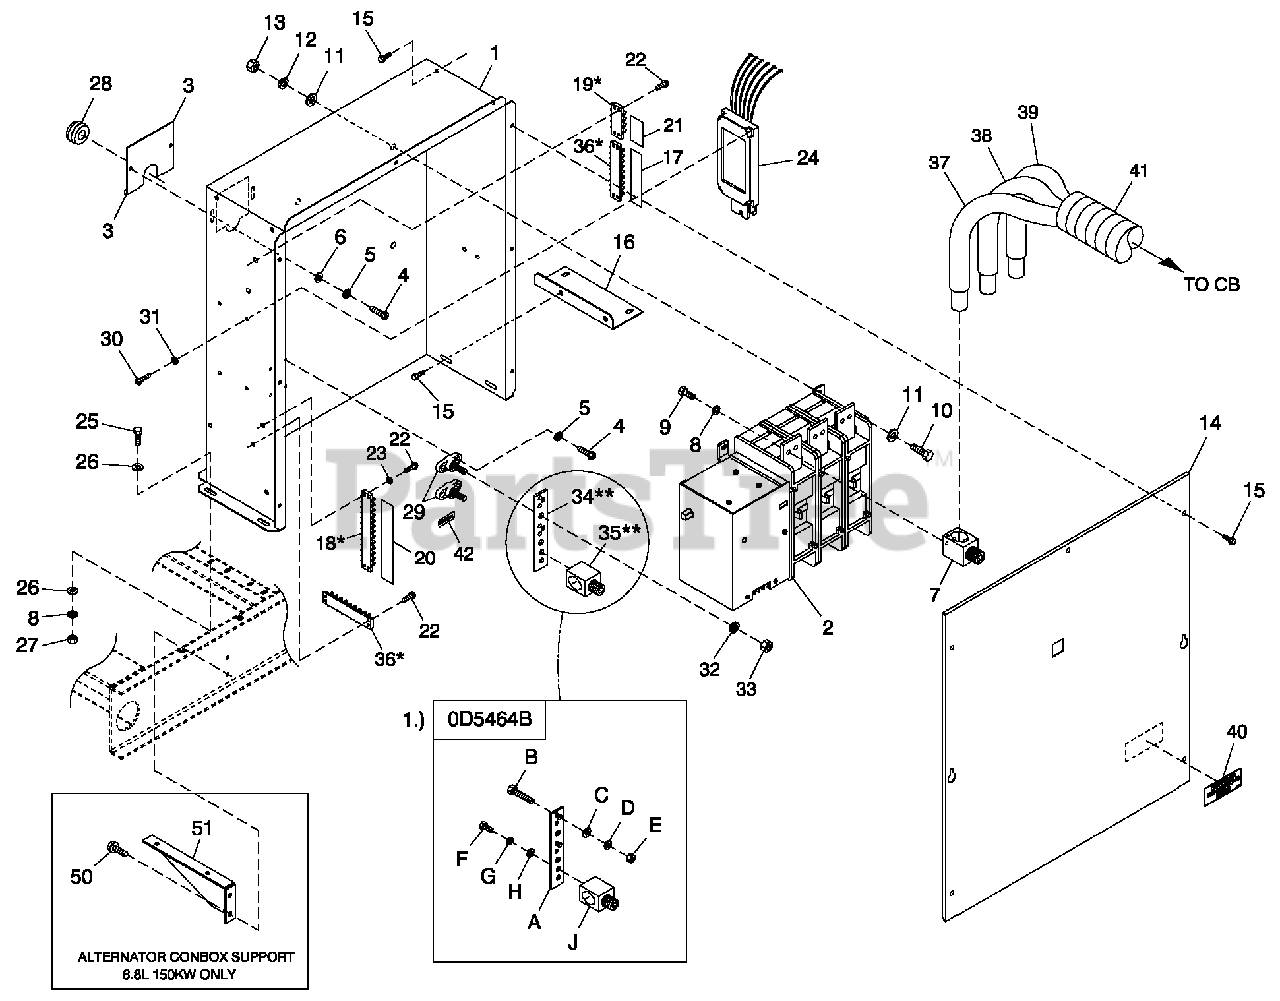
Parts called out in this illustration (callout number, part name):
1	CONBOX CONTACTOR 400A
2	CONTACTOR 400A 3P AC CL DC TR
3	PLATE WIRE SNGLGALV
4	SCREW PHTT M5-0.8 X 16 ZYC
5	WASHER LOCK M5
6	WASHER FLAT M5
7	LUG SLDLSS 600/250-1/0X1/4-28
8	WASHER LOCK M6-1/4
9	SCREW HHC 1/4-28 X 5 /8 .625TH
10	SCREW HHC M8-1.25X 20 G8.8
11	WASHER FLAT 5/16-M8 ZINC
12	WASHER LOCK M8-5/16
13	NUT HEX M8-1.25 G8 CLEARZINC
14	COVER CONTACTOR 400A
15	SCREW THF M6-1 X 16 N WA Z/JS
16	MOUNT CONTACTOR
17	DECAL GEMINI PLS CONNECTIONS
18	BLOCK TERM 2 0A 12 X 6 X1100V
19	BLOCK TERM 20A 6 X 3 X1100V
20	DECAL CUSTOMER CONNECTION
21	DECAL CUSTOMER CONNECTION 120V UTILITY
22	SCREW PHTT #6-32 X 1/2 ZYC
24	ASSY PCB 3PH VOLT DIV 480V L-L
25	SCREW HHC M6-1.0X 20 G8.8
26	WASHER FLAT 1/4-M6 ZINC
27	NUT HEX M6X 1.0 G8 YEL CHR
28	GROMMET 1.25 X .25 X .75
29	JUNCTION BLOCK 3/8-16
30	SCREW PPHM M4-0.7 X 10
31	WASHER LOCK #8-M4
32	WASHER LOCK 3/8
33	NUT HEX 3/8-16 STEEL
34	BUS BAR NEUTRAL BLOCK 390
35	LUG SLDLSS 600/250-1/0 X 1/4-28
36	BLOCK TERM 20A 8 X 6 X1100V
37	ASSY WIRE #282 E1 3/0 76.0"
38	ASSY WIRE #283 E2 3/0 76.0"
39	ASSY WIRE #284 E3 3/0 74.0"
40	DECAL CUSTOMER CONNECT INSIDE
41	CONDUIT FLEX 2.0" ID
42	DECAL NEUTRAL
50	SCREW THF M6-1X16 N WA Z/JS
51	SUPPORT CONBOX TRANSFER SWITCH
A	BUS BAR NEUTRAL BLOCK 390
B	SCREW HHC M8-1.25 X 45 G8.8 FT
C	WASHER FLAT 5/16-M8 ZINC
D	WASHER LOCK M8-5/16
E	NUTHEXM8-1.25 G8YEL CHR
F	WASHER FLAT 1/4-M6 ZINC
G	WASHER LOCK M6-1/4
H	SCREW HHC 1/4-28 X 5 /8 .625TH
J	LUG SLDLSS 600/250-1/0 X 1/4-28
